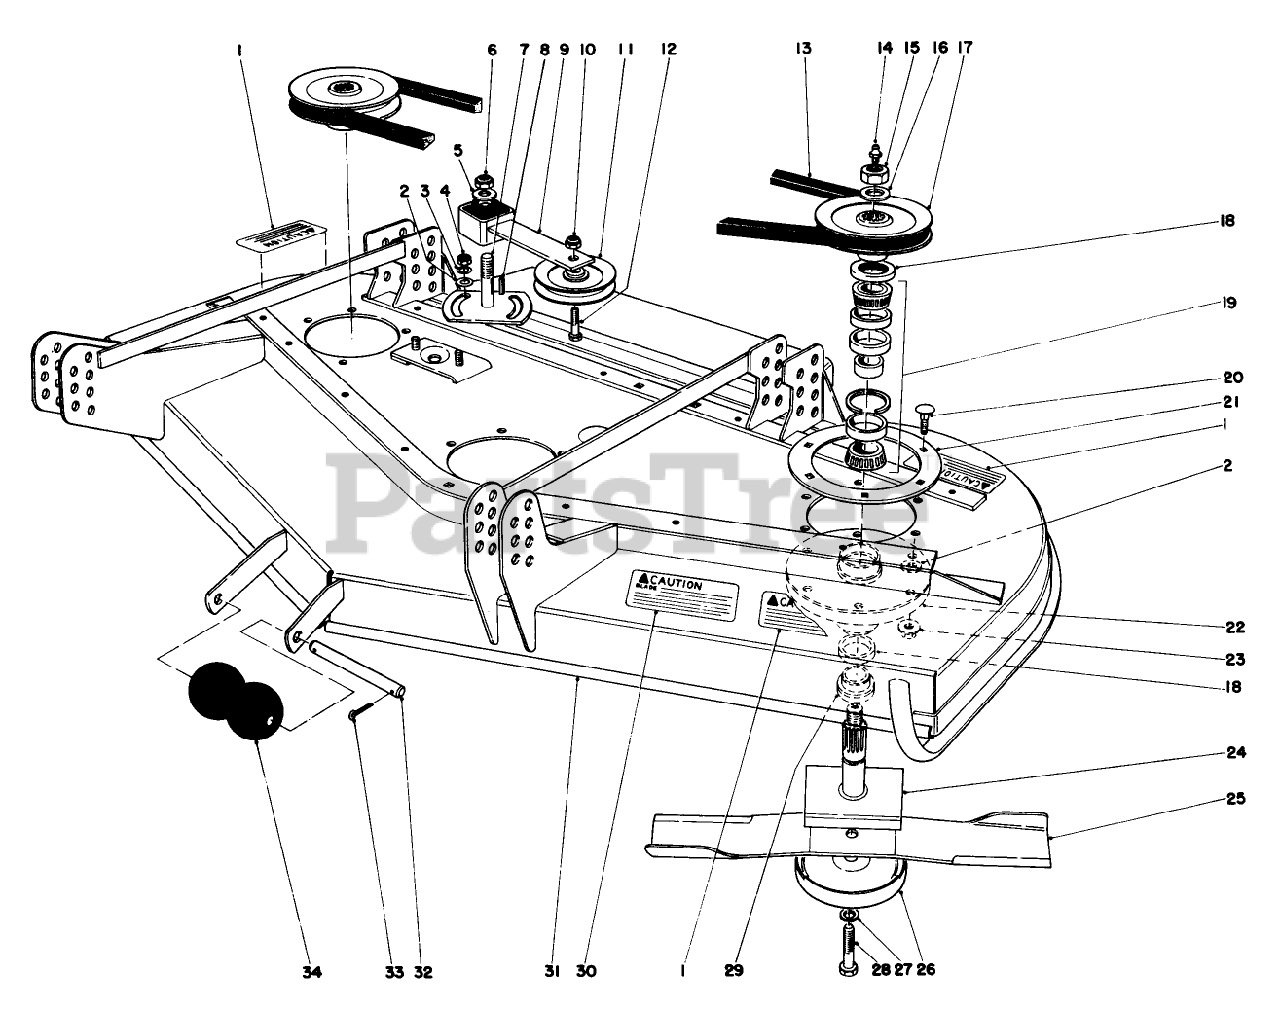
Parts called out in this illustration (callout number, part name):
1	DECAL-CAUTION, BLADE
2	WASHER-FLAT
3	WASHER-LOCK
4	NUT-JAM
5	WASHER-FLAT
6	NUT-LOCK, NI
7	PLATE-IDLER
8	KEY-SQUARE
9	IDLER ARM ASM
10	NUT-HEX
11	Idler Pulley
12	SCREW-HH
13	V-BELT
14	FITTING-GREASE
15	NUT-HEX
16	WASHER
17	PULLEY AND HUB ASM
18	SEAL-OIL
19	BEARING ASM
20	SCREW-CARR
21	SUPPORT-DECK, RING
22	Housing-Spindle
23	NUT-HF
24	SHAFT
25	Blade
26	Cup-Scalp
27	WASHER-LOCK
28	SCREW-BLADE
29	SPACER
30	Decal-Caution
31	CUTTER DECK WA RO
32	SHAFT-ROLLER
33	PIN-COTTER
34	ROLLER
